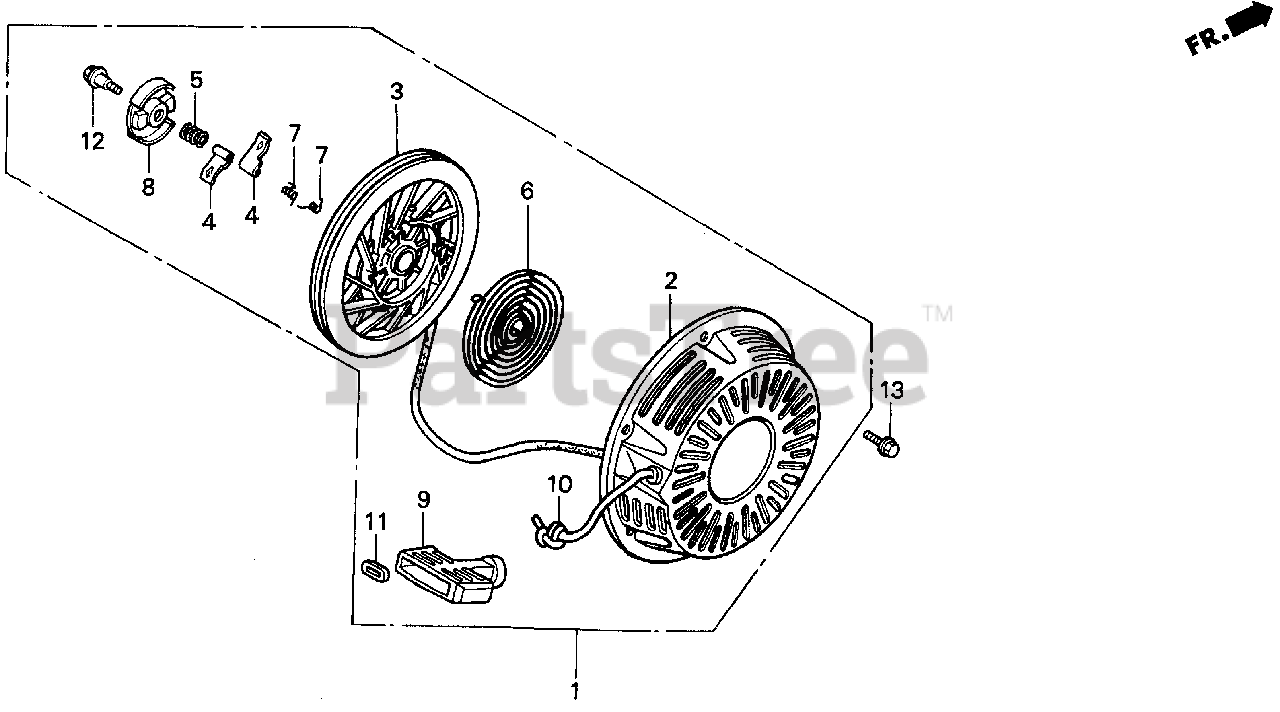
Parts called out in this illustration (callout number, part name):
1	STARTER ASSY., RECOIL *R280* (POWER RED)
2	CASE, RECOIL STARTER *R280* (POWER RED)
3	PULLEY, RECOIL STARTER
4	RATCHET, STARTER
5	SPRING, FRICTION
6	SPRING, STARTER RETURN
7	SPRING, RATCHET
8	RETAINER, SPRING
9	GRIP, STARTER
10	ROPE, RECOIL STARTER (#6X64") (N/A: USE P/N 08560-ZG921-11)
11	GRIP, REINFORCEMENT
12	SCREW, CENTER
13	BOLT, FLANGE (6X8)
